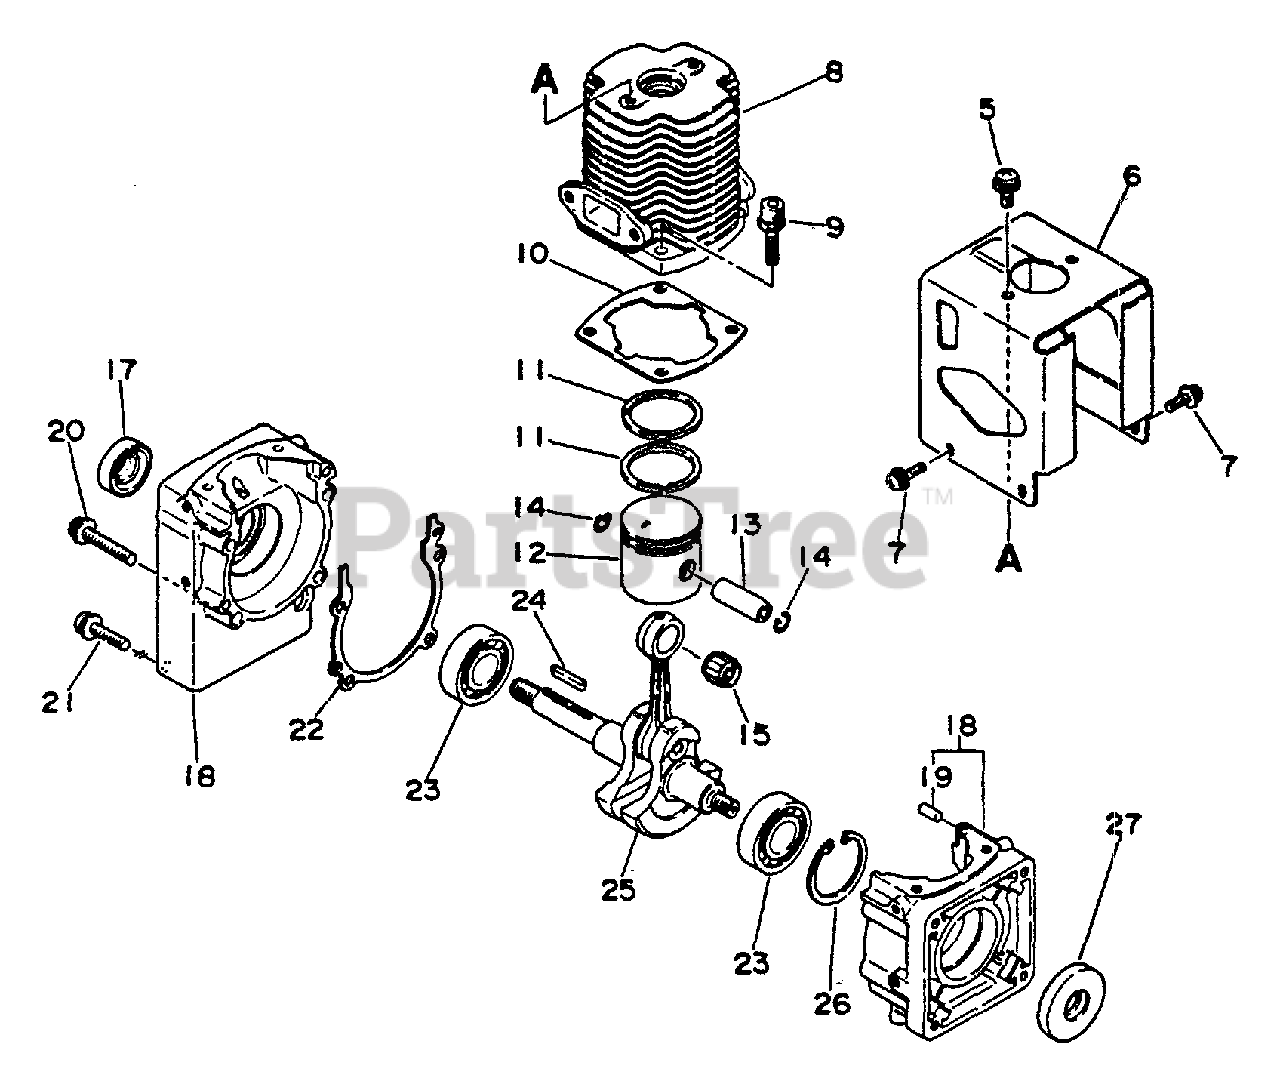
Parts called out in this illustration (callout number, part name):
5	SCREW 5×10
6	COVER, CYLINDER
7	SCREW 4×14
8	CYLINDER
9	BOLT 5×20
10	GASKET, CYLINDER
11	RING, PISTON
12	PISTON
13	PIN, PISTON
14	RING, SNAP 8
15	BEARING, NEEDLE
17	SEAL, OIL
18	CRANKCASE KIT
19	PIN, LOCATING 4
20	SCREW 5×30
21	SCREW 5×20
22	GASKET, CRANKCASE
23	BEARING, BALL 6202
24	KEY
25	CRANKSHAFT
26	RING, SNAP 35
27	SEAL, OIL 18
